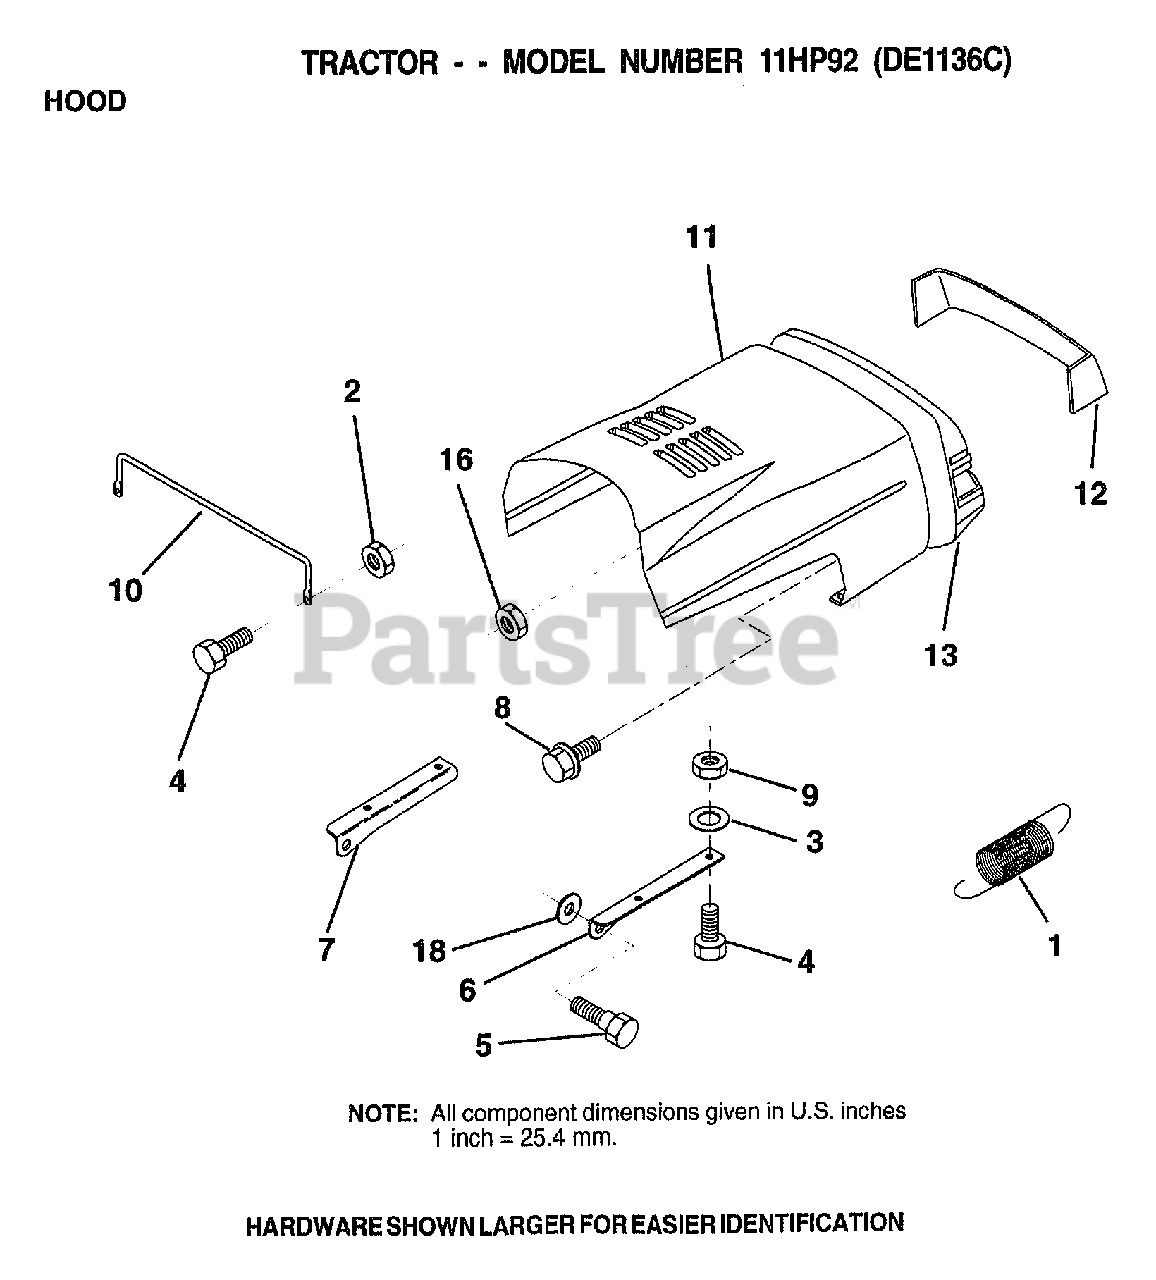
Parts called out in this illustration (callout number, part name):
1	EXT SPRING
2	NUT
3	WASHER
5	BOLT.SHLD.5/16-18
6	BRKT HOOD RH
7	BRKT HOOD LH
8	"SCREW,HWHD.HI-LO#13-16X3/4"
9	NUT
10	"BRACE,HOOD"
12	LENS.LR.JET.GRAY
13	GRILLE.LR.BLACK
16	NUT
18	WASHER
